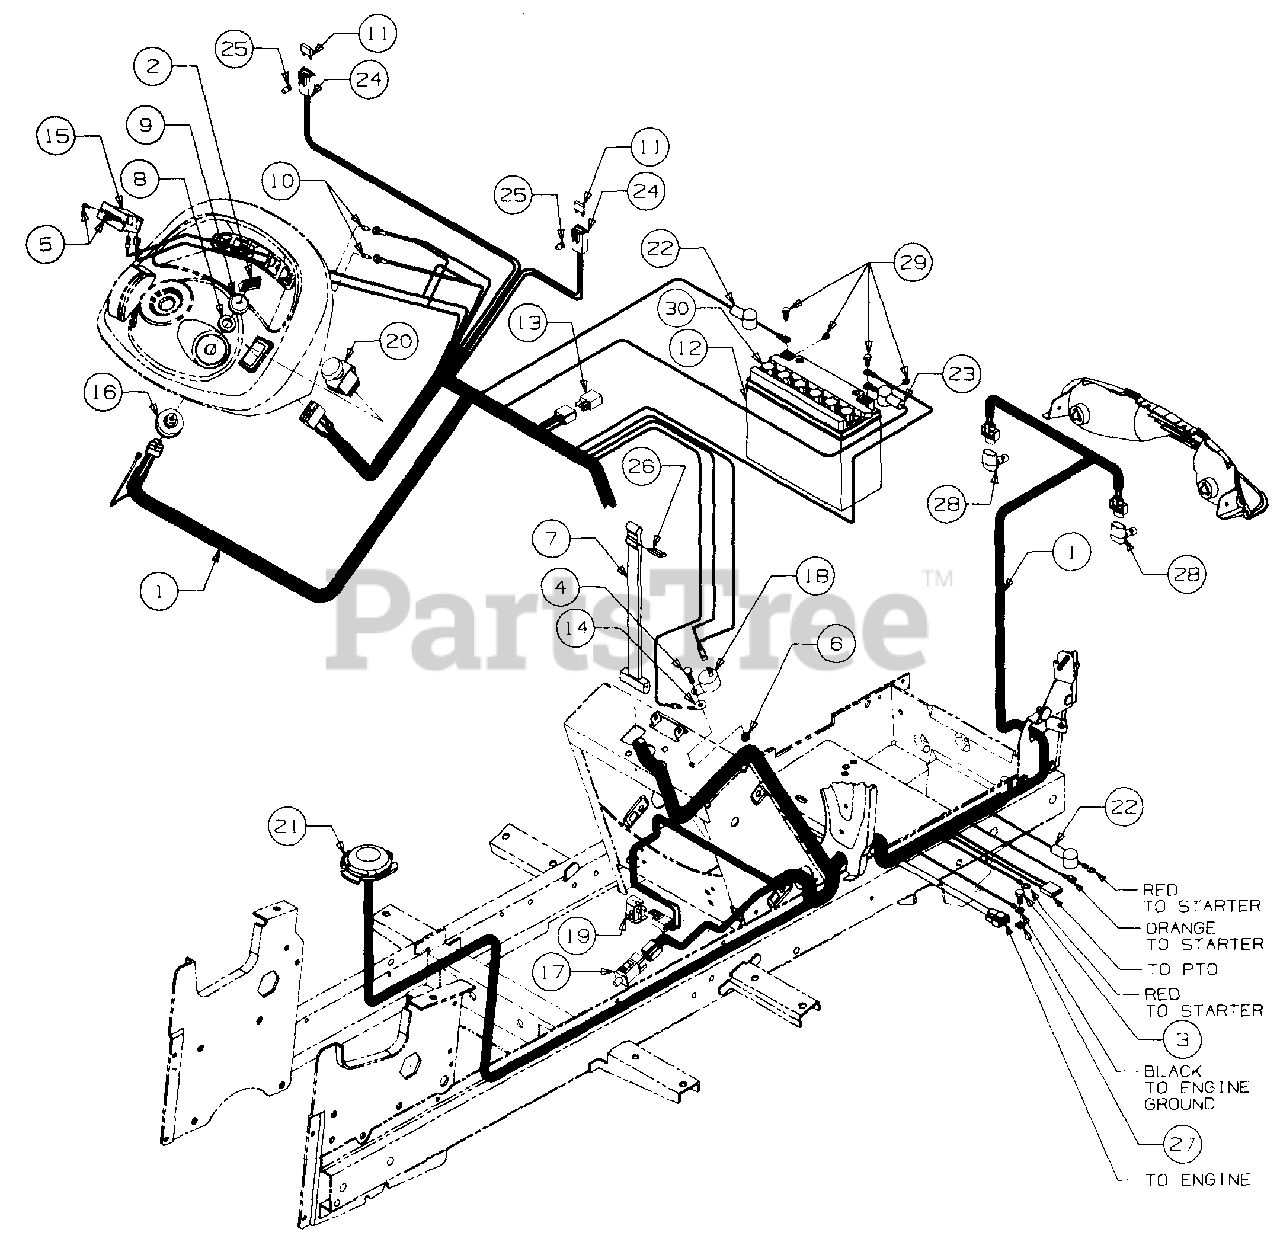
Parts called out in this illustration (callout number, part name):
1	Main Harness
2	Key, Ignition
3	Screw, Hex Cap, 5/16-24 x .62 Lg
4	Screw, Hex Cap, 1/4-20 x 1.0 Lg
5	Screw, Truss Hd Tapp, #6 x .62 Lg
6	Nut, Hex Sems, 1/4-20
7	Strap, Battery Retainer
8	Nut, Ignition Switch
9	Cap, Ignition Switch
10	Bulb, Indicator
11	Fuse, 20 Amp
13	Relay
14	Lug, Quick Connect
15	Hour Meter
16	Switch, Ignition
17	Switch, Interlock (Brake)
18	Indicator, Voltage
19	Switch, Snap Mount - Normally Closed (Reverse)
20	Switch, PTO
21	Switch, Seat
22	Cover, Terminal Red
23	Cover, Terminal Black
24	Holder, Fuse
25	Clip, Fuse Holder Mtg
26	Hook, Wire Rectangular
27	Washer, External Lock, 5/16
28	Bulb, Head Lamp
29	Bolt, Battery
30	Cap, Battery
